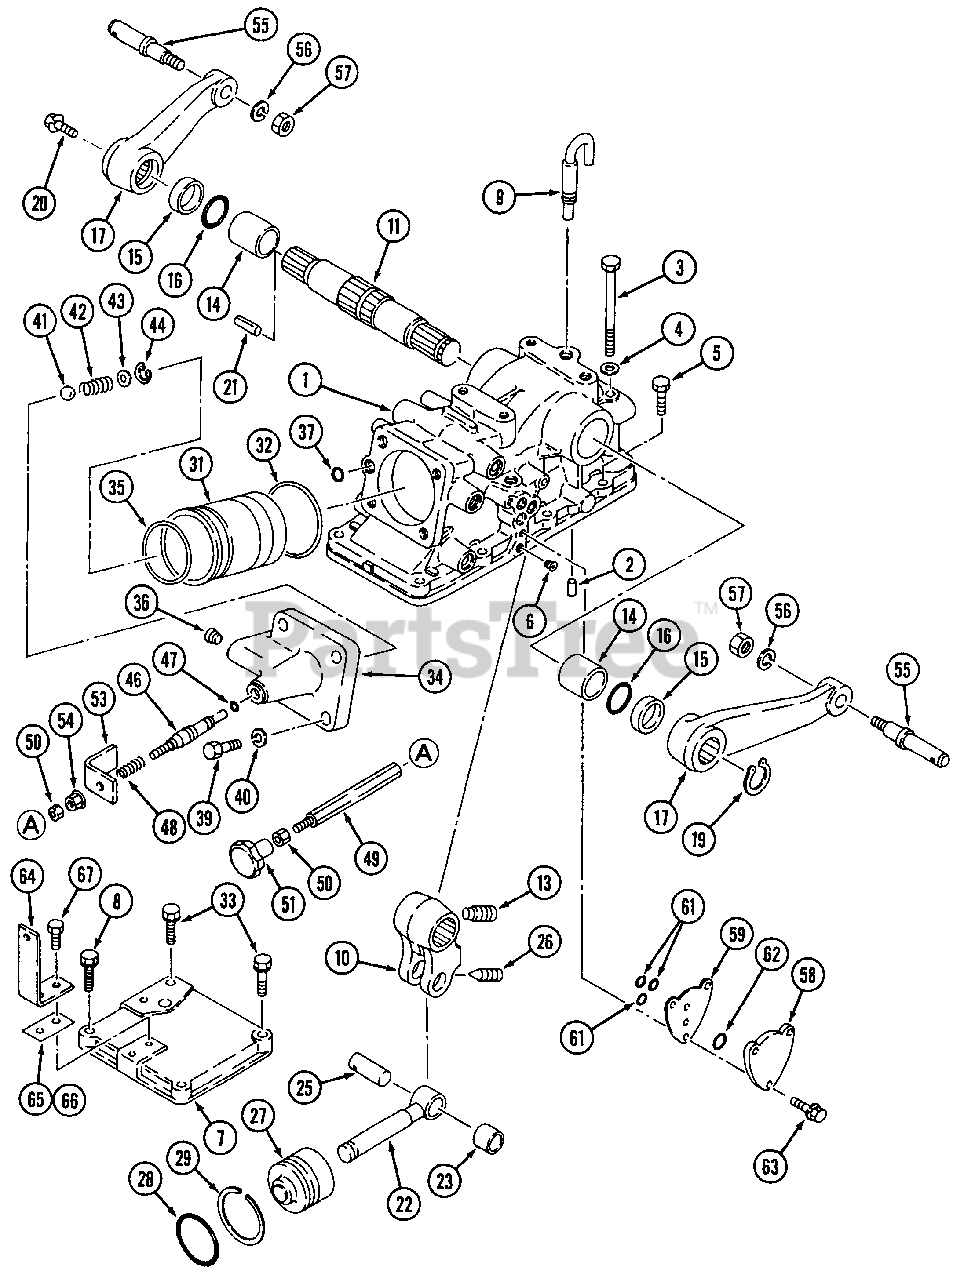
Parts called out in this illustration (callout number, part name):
1	Case, Hydraulic
7	Cover
11	Shaft, Hydraulic
29	Ring, Back Up
31	Cylinder, Hydraulic
34	Head, Cylinder
53	Lever, Stopper
55	Pin, Lift Arm
